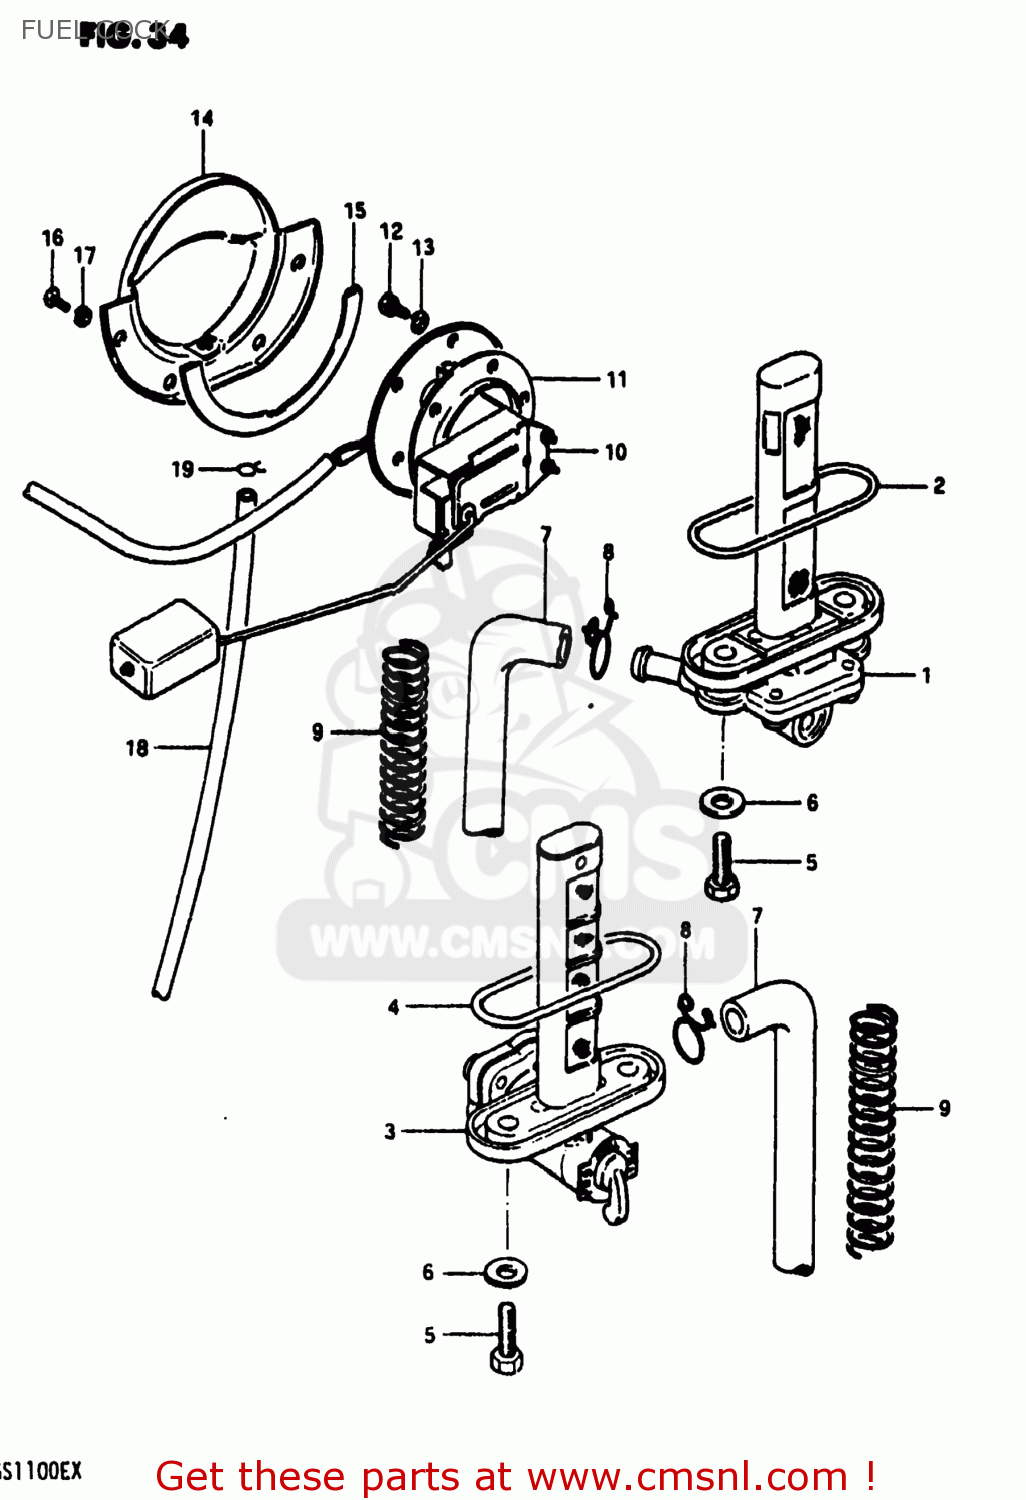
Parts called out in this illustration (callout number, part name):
1	COCK ASSY,FUEL
2	GASKET (NAS)
3	COCK ASSEMBLY,FUEL
4	O RING
5	SCREW (6X25)
6	GASKET
7	HOSE
8	CLIP
9	SPRING
10	GAUGE ASSEMBLY,FUEL LEVEL
11	GASKET,FUEL LEVEL GAUGE (NAS)
12	BOLT
13	LOCK WASHER
14	PLATE,FUEL DRAIN
15	GASKET,FUEL DRAIN PLATE (NAS)
16	SCREW
17	LOCK WASHER
18	HOSE,FUEL
19	CLIP
